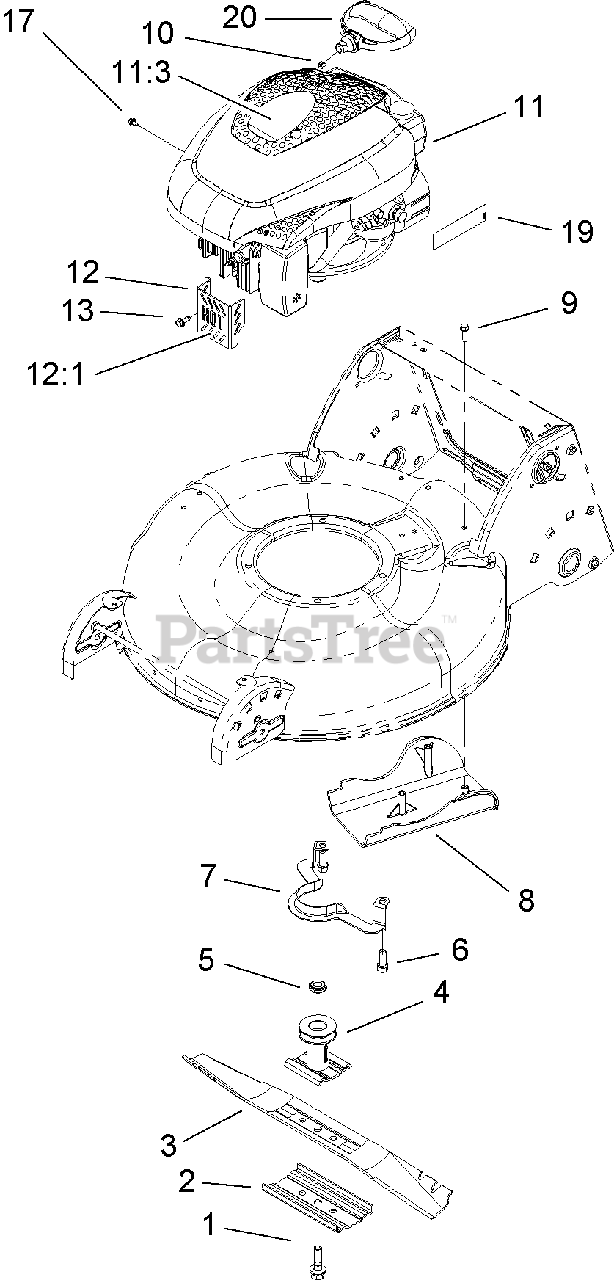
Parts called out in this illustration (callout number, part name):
1	BOLT-BLADE
2	SUPPORT-BLADE
3	BLADE-21 INCH
4	BLADE DRIVER ASM
5	Spacer-Driver
6	SCREW
8	COVER-BELT
9	SCREW-HWH
10	STOP-ROPE
11:3	DECAL-RECOIL
12	MUFFLER GUARD ASM
12:1	DECAL-SURFACE, HOT
13	SCREW-HWH
17	SCREW-HWH
19	DECAL-PRIMER
20	HANDLE-RECOIL
